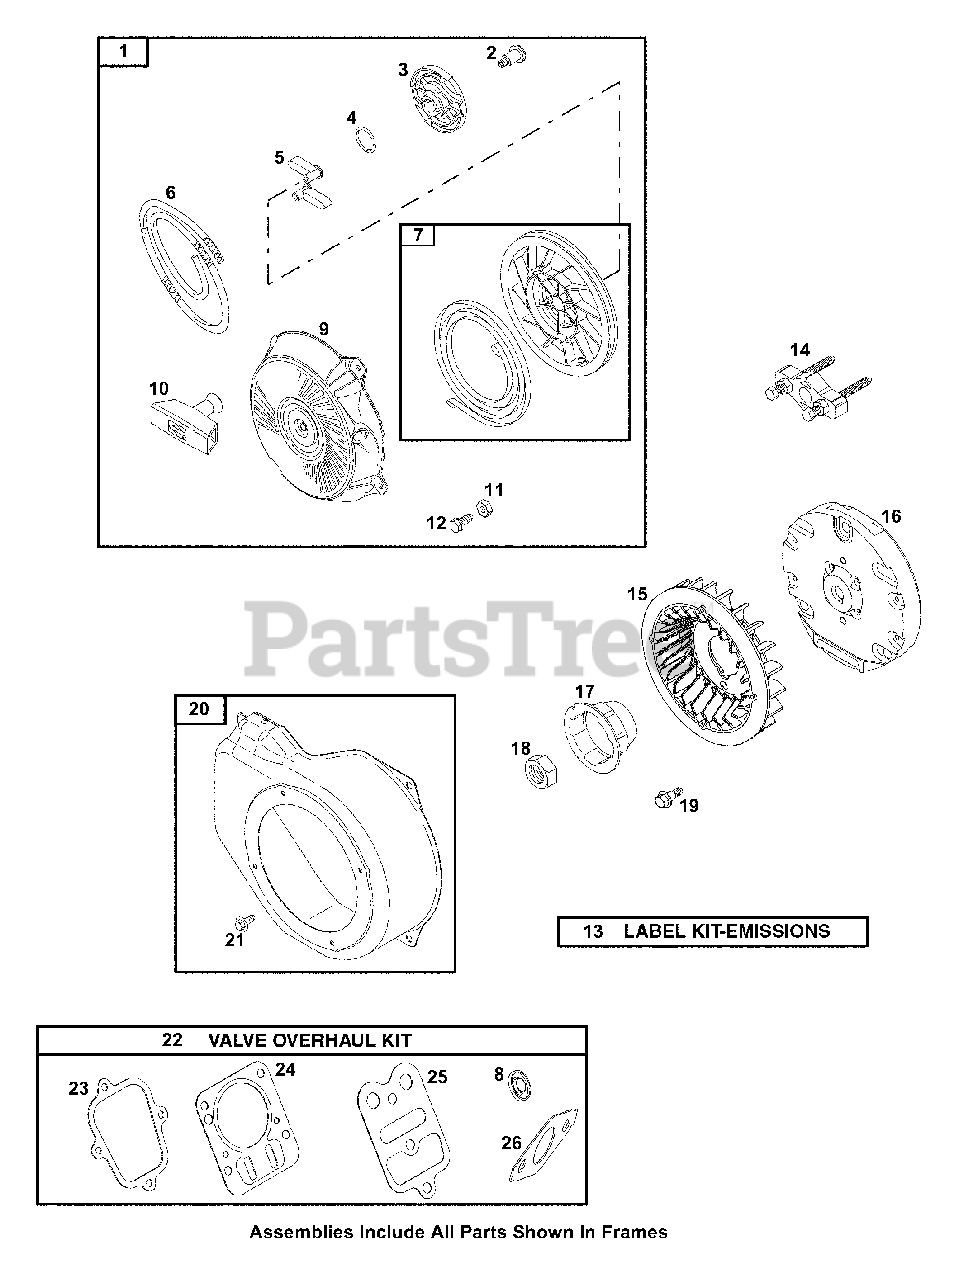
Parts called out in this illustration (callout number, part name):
1	Starter-Rewind
2	Screw (Pawl Friction Plate)
3	Plate-Pawl Friction
4	Spring-Friction
5	Pawl-Ratchet
6	Rope-Starter
7	Pulley/Spring Assembly
8	Seal-Valve
9	Rewind Starter Housing
10	Starter Rope Grip
11	Nut (Rewind Starter)
12	Screw (Rewind Starter)
13	Emissions Label
14	Flywheel Puller
15	Fan-Flywheel
17	Cup-Flywheel
18	Nut (Flywheel)
19	Screw (Flywheel)
20	Housing-Blower
21	Screw (Blower Housing)
22	Kit-Valve Overhaul
23	Gasket-Rocker Cover
24	Cylinder Head Gasket
25	Cylinder Head Plate Gasket
26	Gasket-Intake
